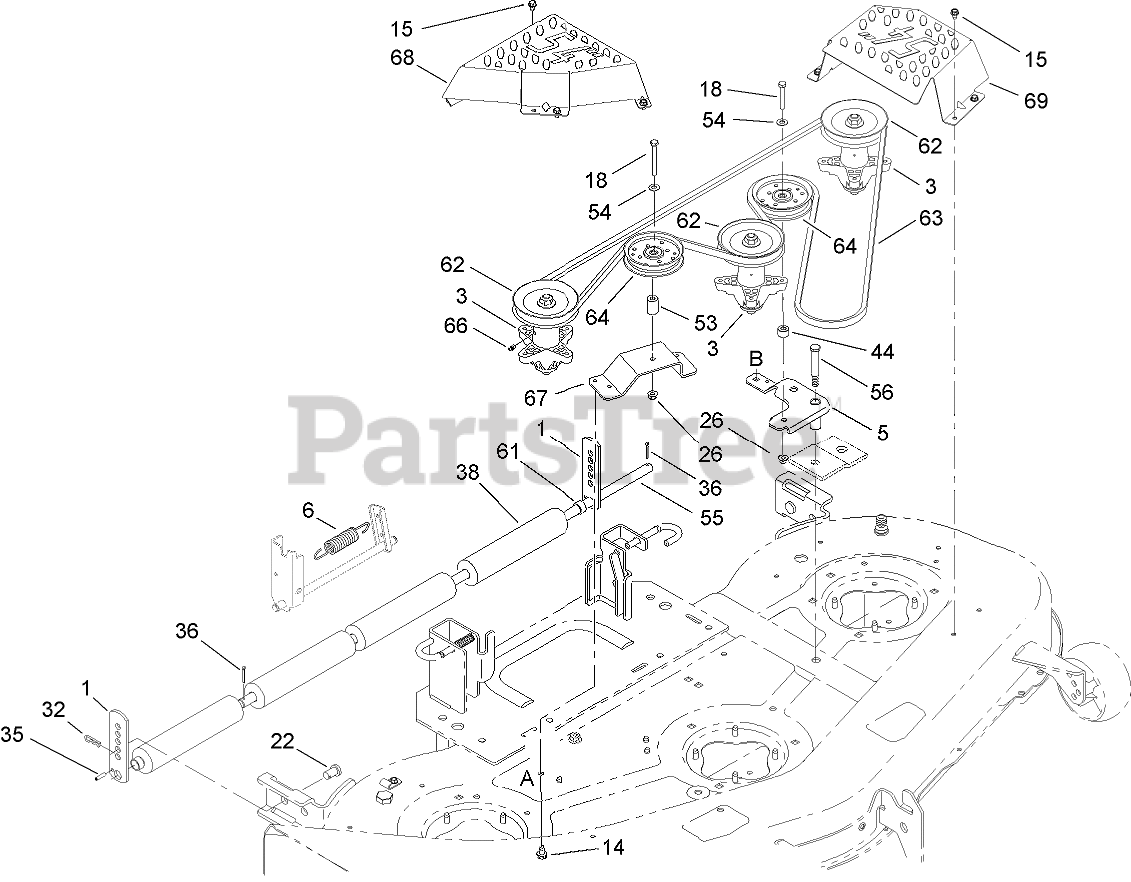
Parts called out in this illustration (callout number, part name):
1	ADJUSTER-HEIGHT
3	SPINDLE ASM
5	IDLER ASM
6	SPRING EXTENSION
14	SCREW-TAP
15	SCREW-TAP
18	SCREW-HH
22	PIN-BRACKET, LIFT
26	NUT-LOCK, FLANGE
32	PIN-HAIR
35	PIN-SPRING
36	PIN-SPRING
38	ROLLER-DECK
44	SPACER
53	SPACER
54	WASHER-ISOMOUNT
55	SHAFT-ROLLER
56	BOLT-SHOULDER
61	SPACER
62	PULLEY-DECK
63	BELT-V, TYPE B
64	PULLEY-IDLER
66	FITTING-GREASE
67	BRACKET-IDLER, STATIONARY
68	COVER-SPINDLE, RH
69	COVER-SPINDLE, LH
